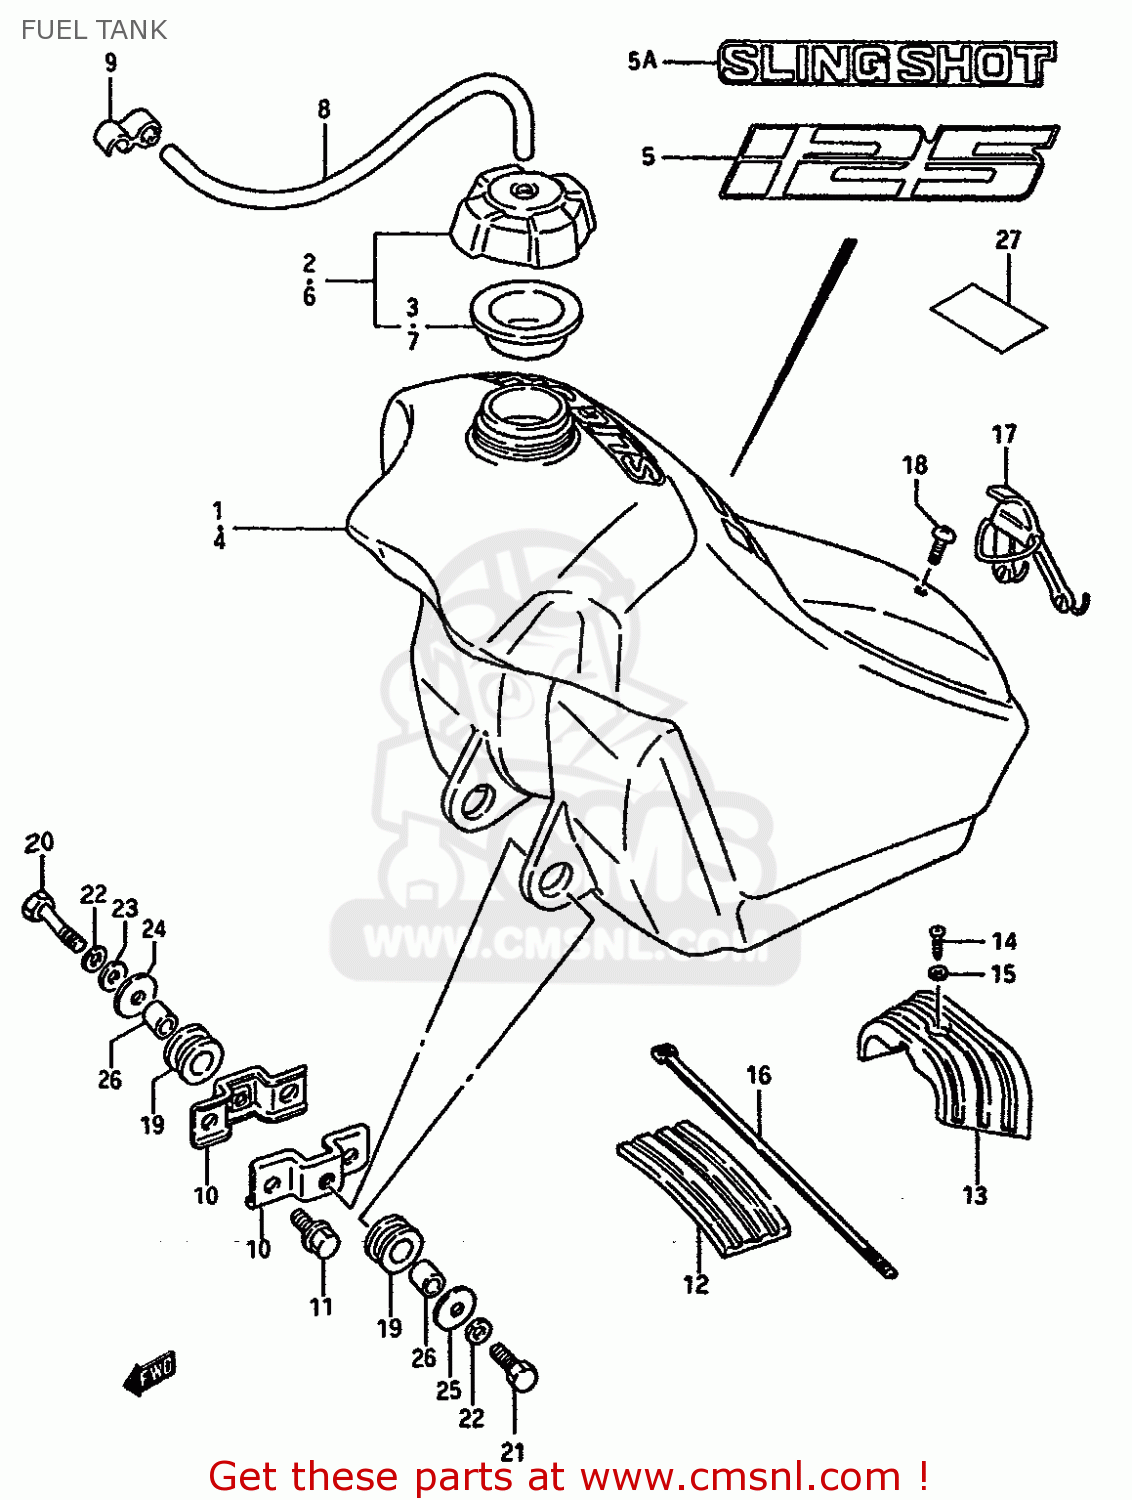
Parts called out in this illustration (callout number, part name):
1	TANK SET,FUEL
2	CAP SET,FUEL TANK
3	GASKET,FUEL TANK CAP (NAS)
4	TANK SET,FUEL
5	TAPE,FUEL TANK (125)
5A	EMBLEM
6	CAP SET,FUEL TANK
7	GASKET,FUEL TANK CAP (NAS)
8	HOSE
9	CLAMP,BREATHER HOSE
10	BRACKET,FUEL TANK
11	BOLT 8X16
12	CUSHION,FUEL TANK UPR FR
13	CUSHION,FUEL TANK,UPPER
14	SCREW
15	WASHER
16	CLAMP
17	BAND,FUEL TANK RR
18	SCREW
19	CUSHION
20	BOLT
21	BOLT
22	LOCK WASHER
23	WASHER
24	WASHER(8.5X26X1.2)
25	WASHER
26	SPACER(8.4X12X12)
27	LABEL,UNLEADED FUEL
